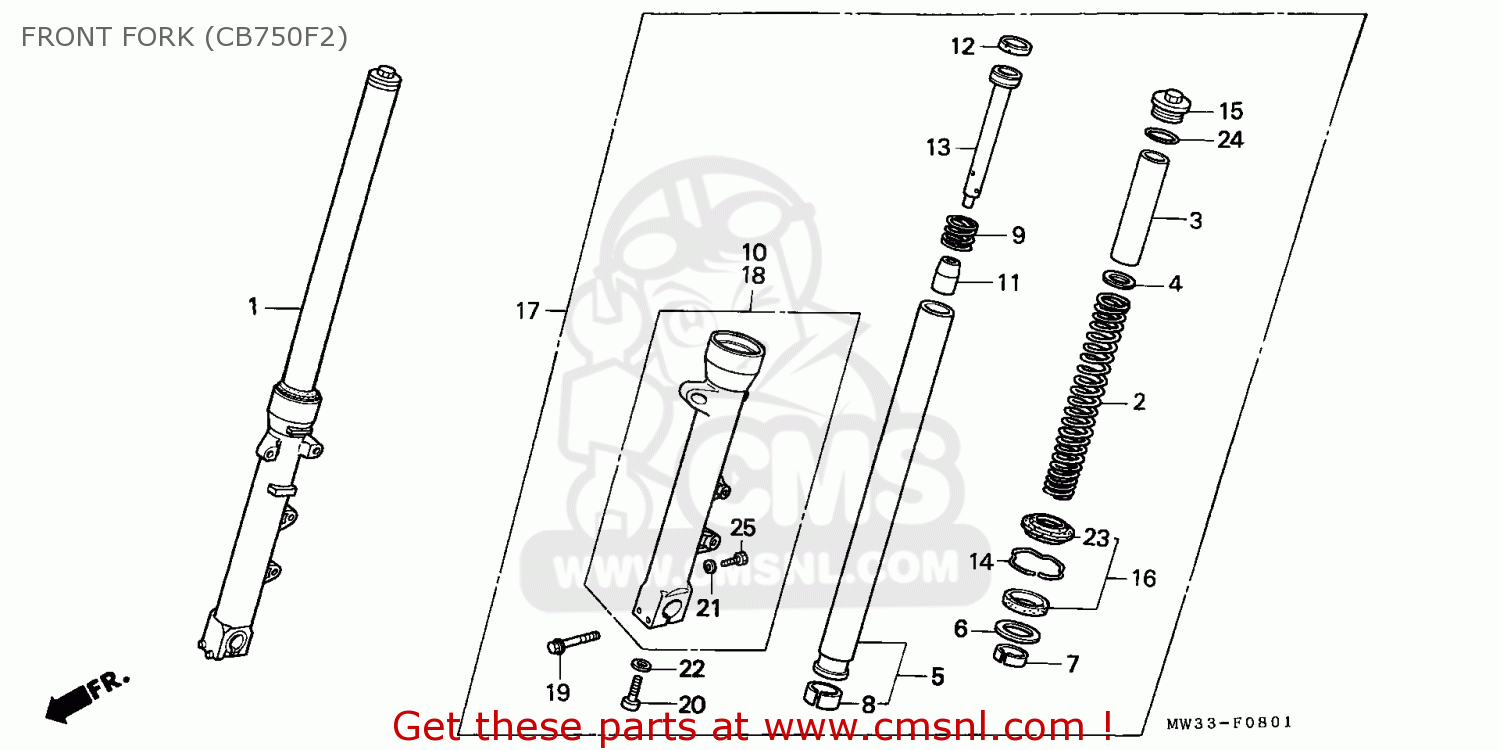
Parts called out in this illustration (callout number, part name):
1	FORK ASSY,R FR
2	SPRING,FR FORK
3	SPRING,FR.FORK
4	SEAT,SPRING
5	PIPE COMP,FR FORK
6	RING,BACK UP
7	BUSH,GUIDE
8	BUSH,SLIDER (SHOW
9	SPG,FR.REBOUND
10	CASE COMP,R BOT
11	PIECE,OIL LOCK (S
12	RING,PISTON (SHOW
13	PIPE,SEAT
14	RING,OIL STOP.
15	BOLT,FR FORK
16	SEAL SET,FR.FORK
17	FORK ASSY,L FR
18	CASE COMP,L BOT
19	BOLT,FLANGE,8X45
20	BOLT,SOCKET 8MM
21	PACKING, DRAIN
22	WASHER,SPL.,8MM
23	SEAL,DUST
24	O-RING
25	BOLT,HEX.,6X8
